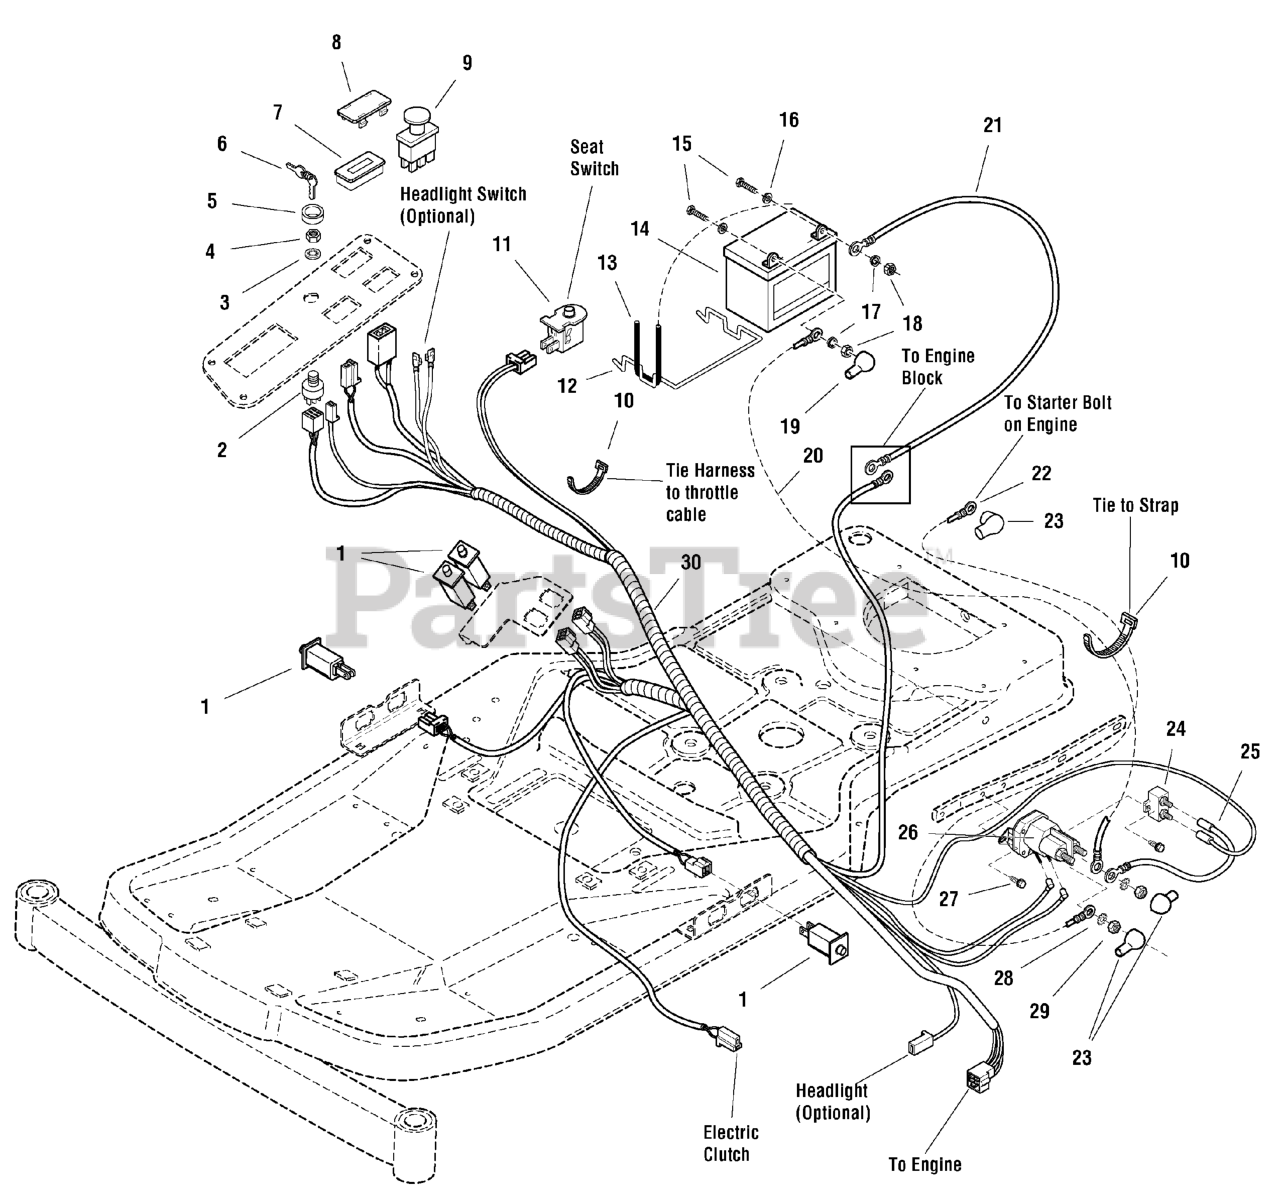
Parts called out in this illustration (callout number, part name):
1	SWITCH, Push Button
2	SWITCH ASSEBMLY, Ignition, (Includes Ref. Nos. 3, 4, 5 & 6)
3	LOCKWASHER, Internal Tooth, Ignition Switch
4	NUT, Hex Flange, 5/8-32, Ignition Switch
5	COVER, Ignition Switch
6	KEYS (Set of 2 Keys)
7	METER, Hour Digital, with Oil & Lube Alarms
8	PLUG, Hole
9	SWITCH, PTO, Push/Pull
10	TIE, Self Locking
11	SWITCH, Push Button, Seat Switch
12	BRACE, Battery
13	STRAP, Black
14	BATTERY, 12 Volt, 6 Cell, 340 Amps
15	CAPSCREW, Hex Head, 1/4-20 x 3/4 G5
16	WASHER, 1/4
17	LOCKWASHER, Spring, 1/4
18	NUT, Hex, 1/4-20
19	BOOT, Insulator
20	CABLE, #6 x 25, 2 Ring Terminals
21	CABLE, #6 x 31, 2 Ring Terminals
22	CABLE, #6 x 37-3/4, 2 Ring Terminals
23	COVER, Terminal
24	BREAKER, Circuit, 12 Volt, 20 Amps with Tab
25	WIRE, 12 GA
26	SOLENOID, 4 Pole, 12 Volt DC
27	CAPSCREW, Hex Washer Head Taptite, 1/4-20 x 1/2, G5
28	LOCKWASHER, External Tooth
29	NUT, Hex, 5/16-24
30	HARNESS, Wiring
